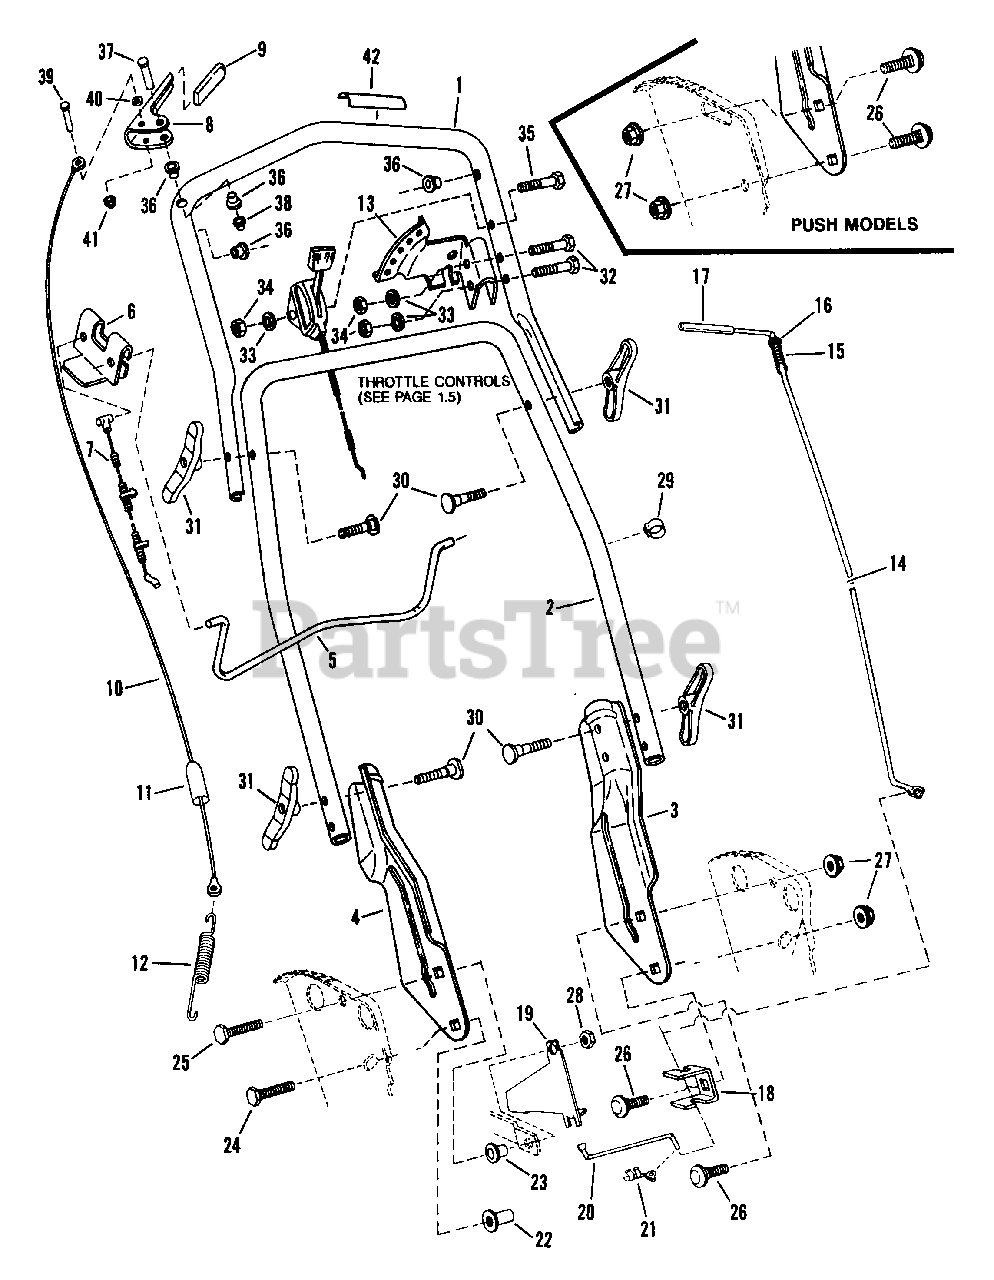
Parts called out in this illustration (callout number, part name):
1	HANDLE, Upper
2	HANDLE, Middle
3	HANDLE, Lower Left Hand
4	HANDLE, Lower Right Hand
5	CONTROL, Blade
6	CLIP, Blade Control
7	CABLE, Blade Control
8	HANDLE, Wheel Drive
9	GRIP, Wheel Drive Handle
10	CABLE, Clutch Pull (includes #11)
11	COVER, Vinyl (included on #10)
12	SPRING, Clutch
13	SECTOR, Speed
14	LEVER, Speed Control
15	SPRING, Speed Control
16	WASHER, 3/8" Flat
17	GRIP, Speed Control Handle
18	ANCHOR, Speed Control
19	GUIDE, Lower V-Belt
20	ROD, Transfer
21	CLIP, Transfer Rod
22	TEE-NUT, 5/16-18
23	BUSHING, Differential
24	BOLT, 5/16-18x3/4 Flange Lock
25	CAPSCREW, 5/16-24x1
26	BOLT, 5/16-18x5/8 Carriage
27	NUT, 5/16-18 Hex Flange Lock
28	NUT, 5/16-24 Center Lock
29	CLIP Cable/Wiring
30	SCREW, 1/4Cx1-7/8 Curved Head
31	WING-NUT, 1/4C
32	CAPSCREW, 1/4-28x1-3/8
33	LOCKWASHER, 1/4 Internal Tooth
34	NUT, 1/4-20 Hex
35	CAPSCREW, 1/4-28x1-3/4
36	BUSHING
37	PIN, Clutch Handle
38	PUSH-NUT (for handle pin)
39	PIN, 1-3/4 LG (Clutch cable)
40	WASHER, #10 Flat
41	PUSH-NUT(for clutch pin)
42	DECAL, Blade Control
